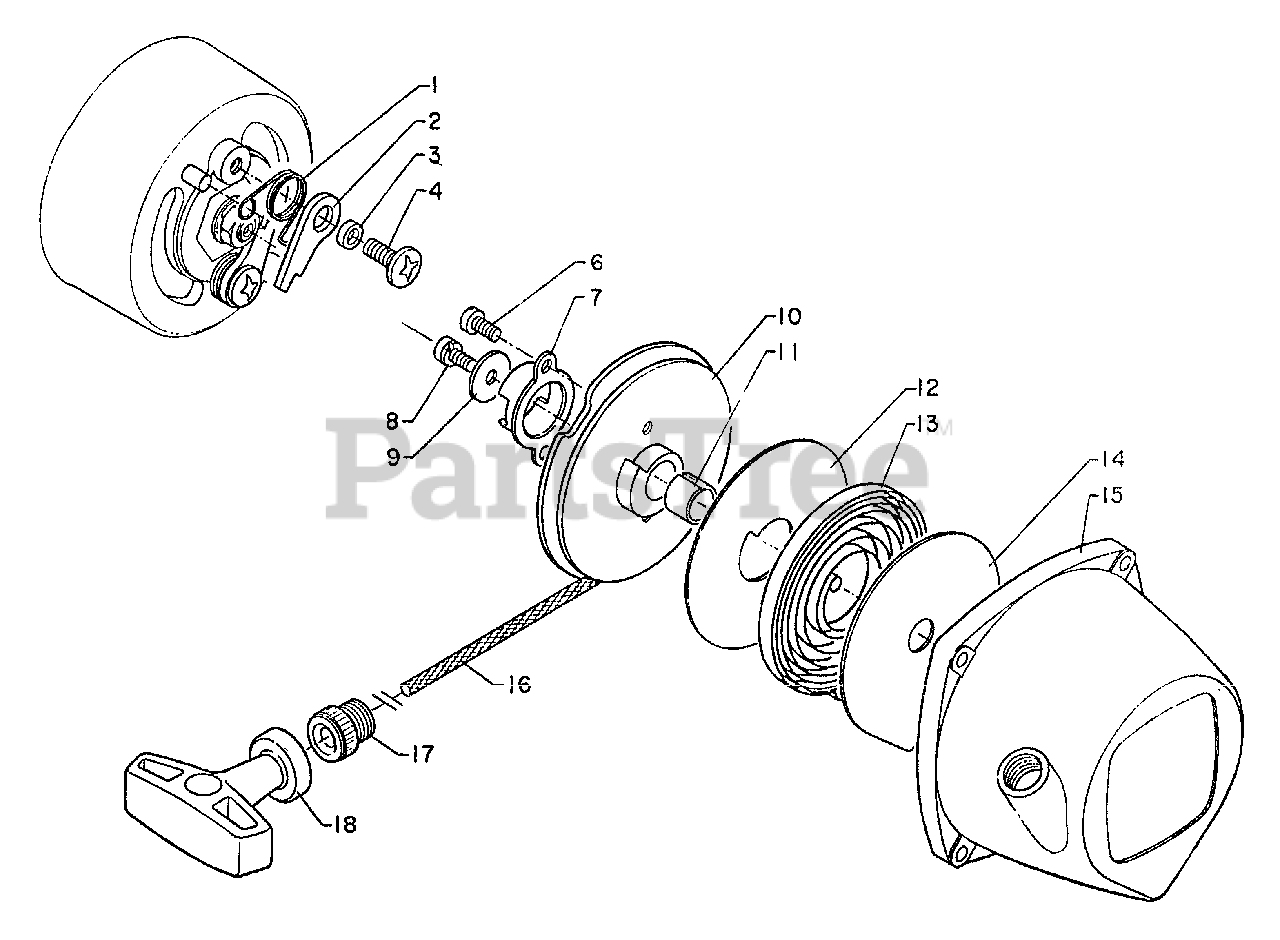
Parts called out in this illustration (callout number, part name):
1	SPRING, RETURN
2	PAWL, STARTER
4	SCREW
6	SCREW - 4X8
7	CATCHER, PAWL
8	SCREW - 4X8
10	REEL, ROPE
12	PLATE, STARTER
13	SPRING, REWIND
14	PLATE, STARTER
15	CASE, STARTER
16	ROPE, STARTER - 3.5X850
17	GUIDE, ROPE
18	GRIP, STARTER
